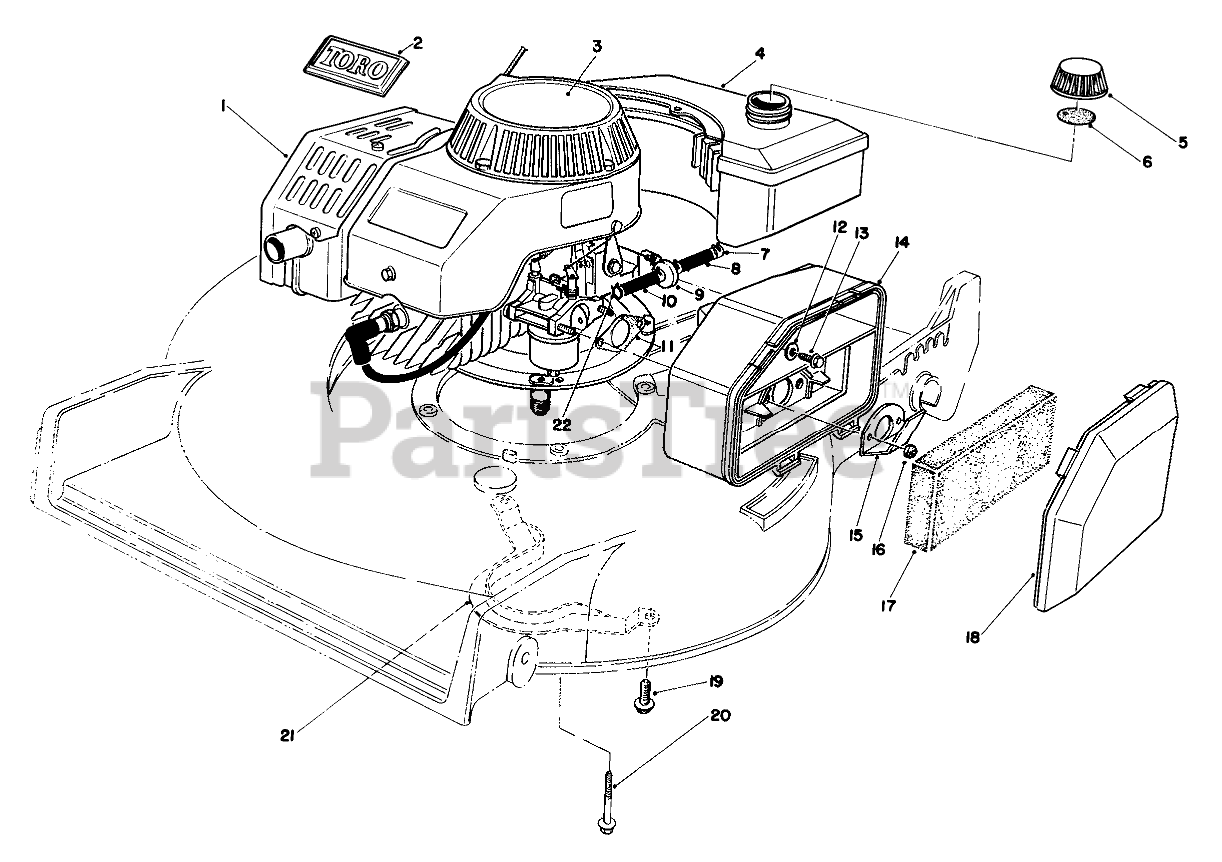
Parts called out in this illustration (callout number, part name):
1	Engine
2	TORO LOGO PLT
3	DECAL
4	Gas Tank Assembly
5	Gas Cap Assembly (Incl. Ref. #6)
6	GAS CAP GASKET
7	CLAMP-FUEL LINE
8	HOSE-FUEL
9	FILTER-FUEL
10	HOSE-FUEL
11	GASKET-AIR CLEANER
12	WASHER-FLAT
13	SCREW-HH
14	AIR CLEANER
15	SPIT BACK DEFLECTOR
16	NUT-LOCK
17	FILTER
18	AIR CLEANER COVER
19	Screw
20	SCREW-HHF
21	BELT GUIDE
22	CLAMP-HOSE
